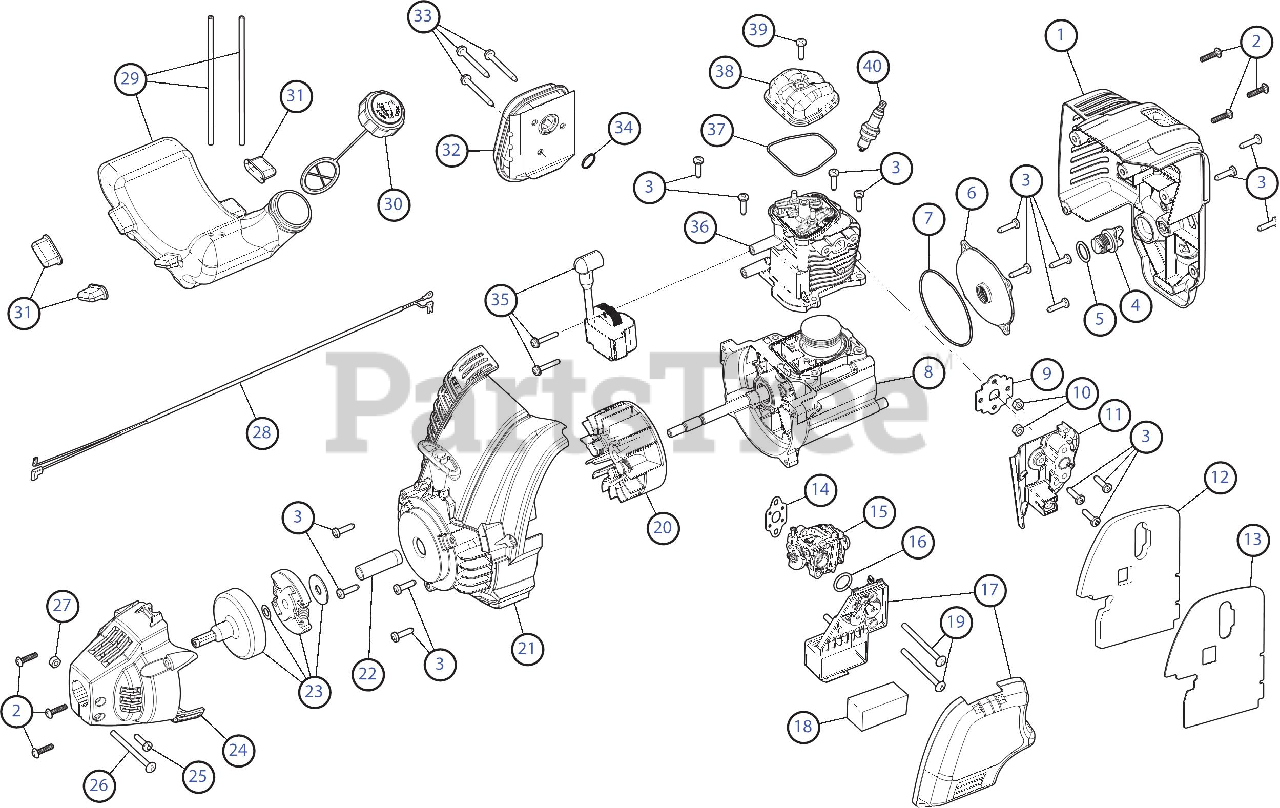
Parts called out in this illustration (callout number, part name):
1	Engine Cover Assembly
2	Cover Screw
4	Oil Plug
5	Oil Plug O-Ring
6	Crankcase Cover
7	Crankcase Cover O-Ring
8	Crankcase Assembly
9	Insulator Gasket
11	Insulator
12	Heat Shield
13	Gasket
15	Carburetor
17	Air Cleaner Cover Assembly
18	Air Filter
20	Flywheel Assembly
21	Starter Housing Assembly
22	Powershaft Spacer
23	Clutch Assembly
24	Clutch Cover
25	Anti-Rotation Screw
26	Clamp Screw
28	Lead Wires
29	Fuel Tank Assembly w/Fuel Lines
30	Fuel Tank Cap
31	Fuel Tank Pads
32	Muffler Assembly
33	Muffler Screw
34	Muffler Gasket
35	Module Assembly
36	Cylinder Assembly
37	Rocker Cover O-Ring
38	Rocker Cover
39	Rocker Cover Screw
40	Spark Plug
